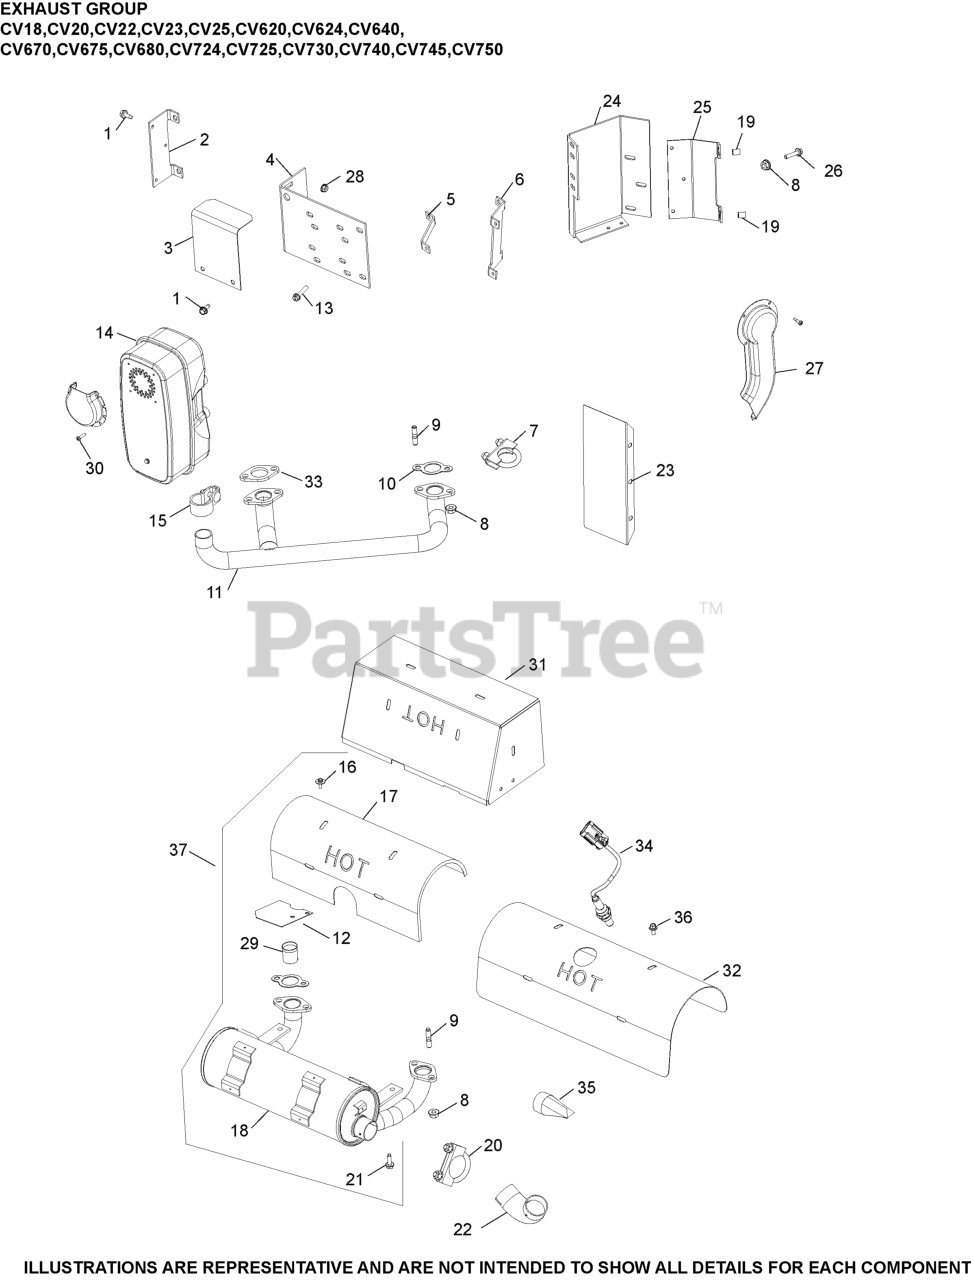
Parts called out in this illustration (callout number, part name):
8	NUT, FLG M8X1.25
9	STUD, M6X1.0X36
10	GASKET, EXHAUST
16	SCREW, SEMS DRILL #8-18X1/2"
17	DUCT, HEAT SHIELD
18	MUFFLER USE 24 068 116-S
28	NUT, FLG M6X1.0
